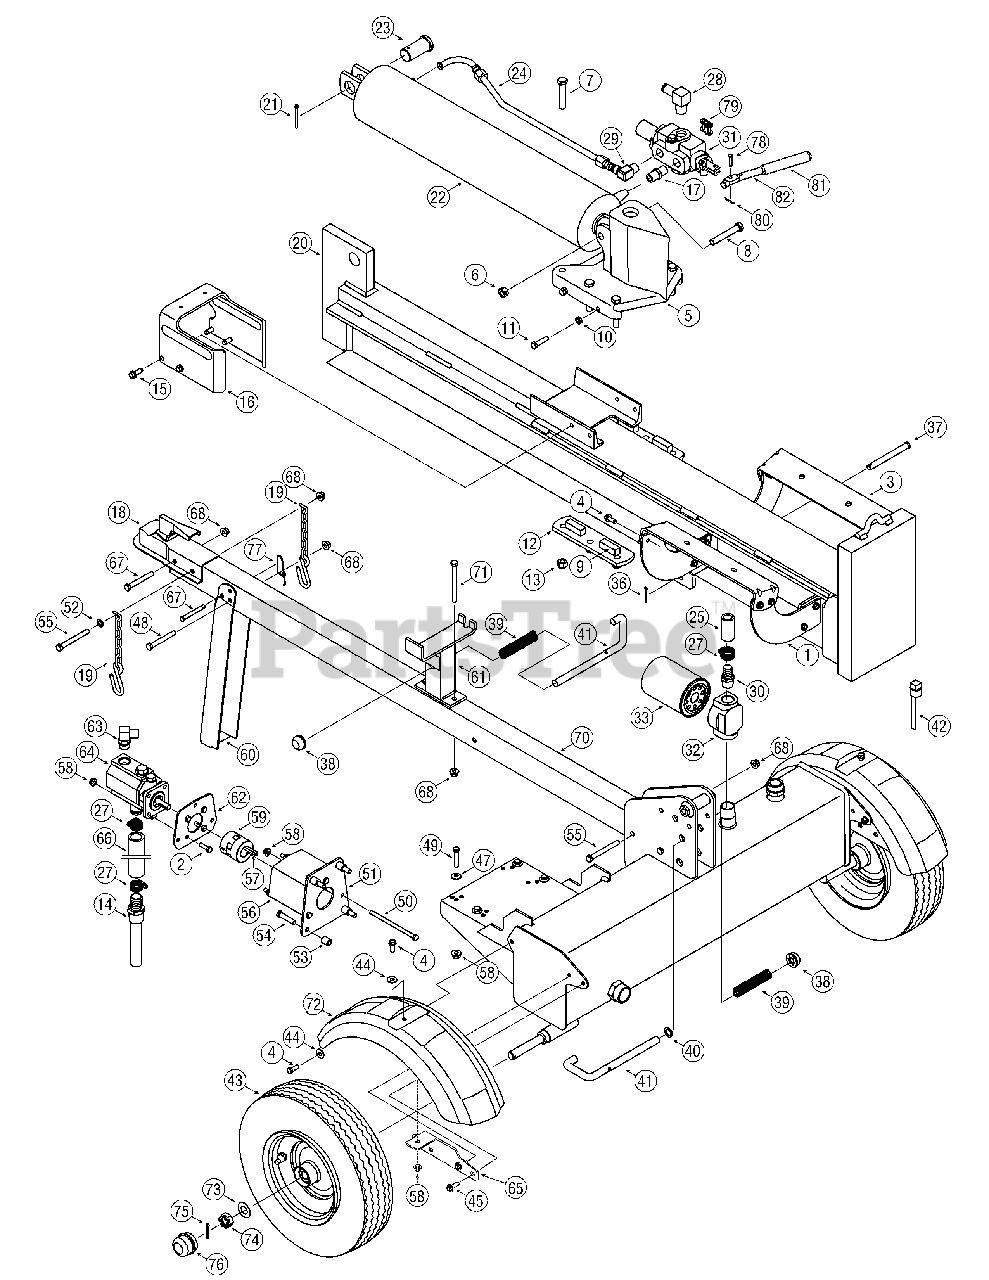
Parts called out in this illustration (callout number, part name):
2	Hex Screw, 5/16-18 x 1.00
4	Self-tap Screw, 5/16-18 x .875
5	Wedge Assembly
6	Lock Nut 1/2-13
7	Hex Cap Screw 1/2-20 x 2.75
8	Hex Cap Screw 1/2-13 x 3.25
9	Adjustable Gib
10	Hex Jam Nut 3/8-24
11	Hex Cap Screw 3/8-24 x 1.5
13	Hex Lock Nut, 1/2-20
14	Inlet Filter
15	Hex Washer Screw 3/8-16 x 1.0
17	Pipe Nipple
18	Hitch Coupler, 2-inch
20	Beam Assembly
21	Cotter Pin
24	Hydraulic Tube
25	Return Hose 3/4" ID x 44"
26	Hose Guard
27	Hose Clamp 5/8"
28	Return Elbow
29	90 Degree Solid Male Adapter
30	3/4" Hose Adapter
31	Control Valve
32	Filter Housing
33	Oil Filter
34	High Pressure Hydraulic Hose
35	Hose Guard
36	Cotter Pin 1/8"
37	Hinge Pin 1/2 x 4.8" Lg.
39	Compression Spring 4"
40	Flat Washer .635 ID x .93 OD
41	Locking Rod
42	Vented Dipstick
43	Wheel Assembly
44	Flat Washer, .343 x .880 x .062
45	Self-tap Screw, 5/16-18 x 1.00
46	Frame Assembly 7.0 Gal
47	Bell Washer, 340 x .872 x .060
48	Hex Cap Screw 3/8-16 x 3.00
49	Hex Cap Screw 5/16-18 x 1.75
50	Hex Cap Screw 5/16-18 x 5.50
53	Spacer, .385 x .623 x .750
54	Hex Cap Screw 3/8-16 x 1.75
55	Hex Cap Screw 3/8-16 x 3.50
56	Coupling Shield
57	Key
58	Hex Flange Lock Nut, 5/16-18
59	Flex Coupling
63	Adapter 7/8-14
64	Pump
66	Suction Hose
67	Clevis Pin, 5/16 x 2.5
68	Flange Lock Nut, 3/8-16
69	Lock Washer 3/8
71	Hex Cap Screw 3/8-16 x 4.0
73	Flat Washer .76" ID x 1.5" OD
74	Slotted Nut 3/4-16
75	Cotter Pin 5/32" x 1-1/4"
77	Spring Pin
78	Clevis Pin
79	Valve Handle Link
80	Cotter Pin
82	Hydraulic Valve Control
